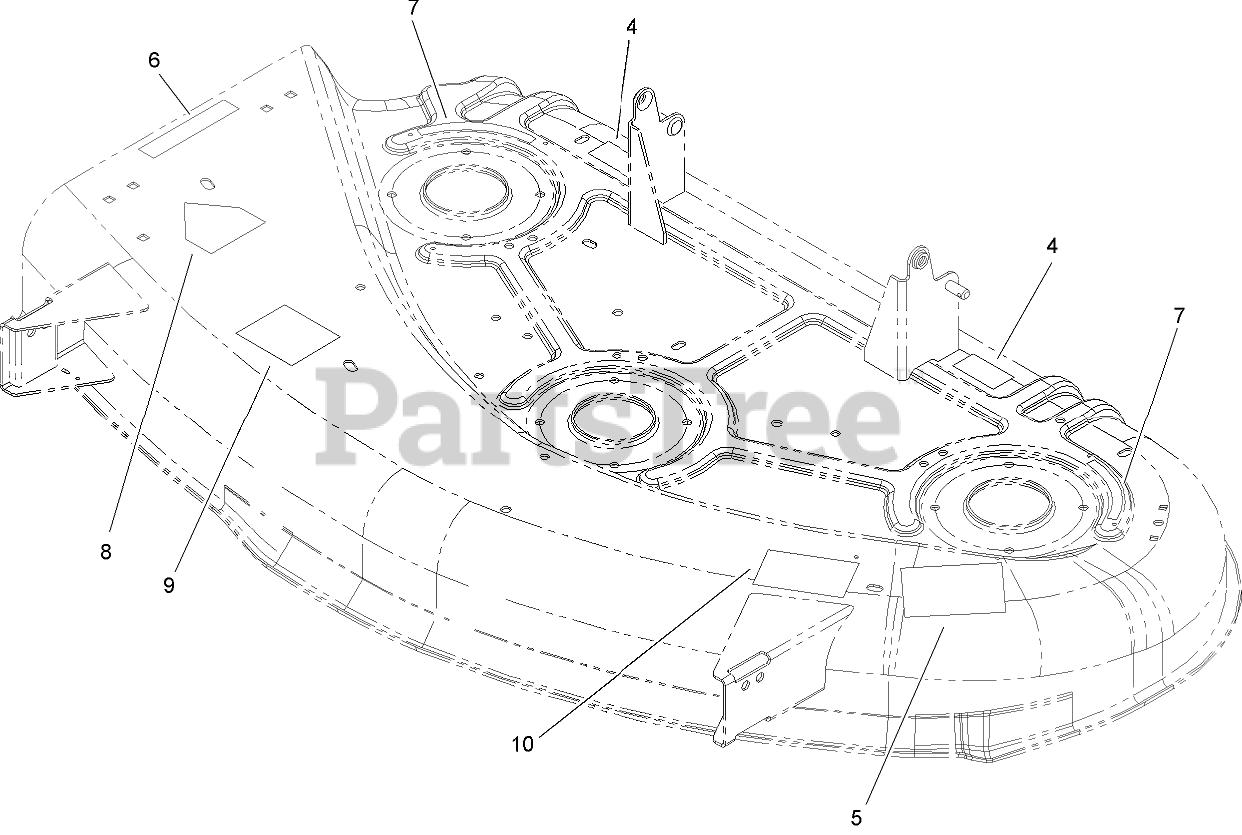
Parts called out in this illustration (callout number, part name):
4	DECAL-WARNING
5	DECAL-DANGER, THROWN OBJECT
6	DECAL-DANGER, DEFLECTOR
7	DECAL-DANGER, SHIELD
8	DECAL-DANGER
9	DECAL-INSTALL, BELT
10	DECAL-ADJUSTMENT, WHEEL
